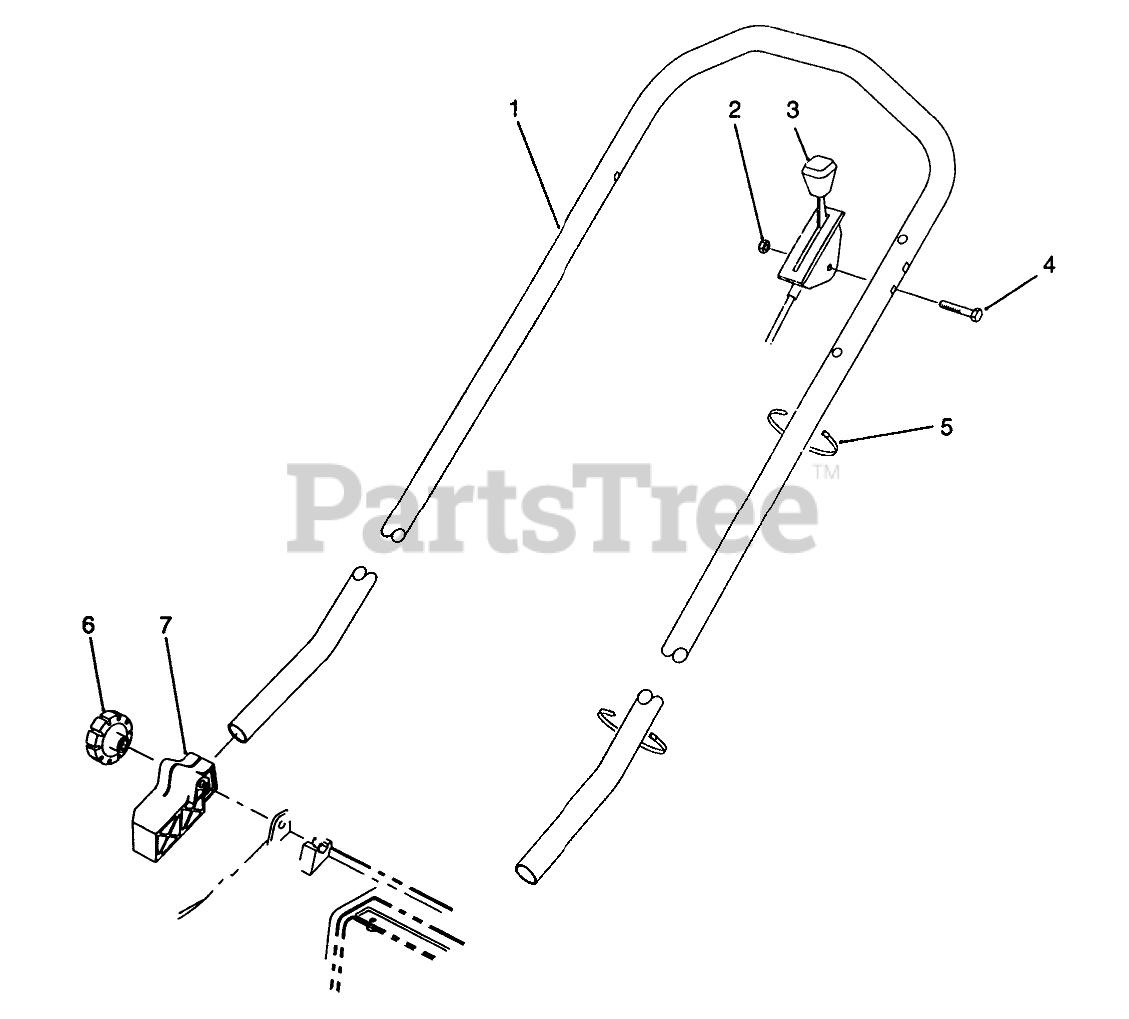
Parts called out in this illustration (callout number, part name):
1	Handle
2	NUT-LOCK, NI
3	Control-Throttle Bend Type #2 Sheath Lg. 44.00 Wire Lg. 2.50
4	SCREW-HANDLE
5	TIE-CABLE
7	MOUNT-HANDLE, LH
